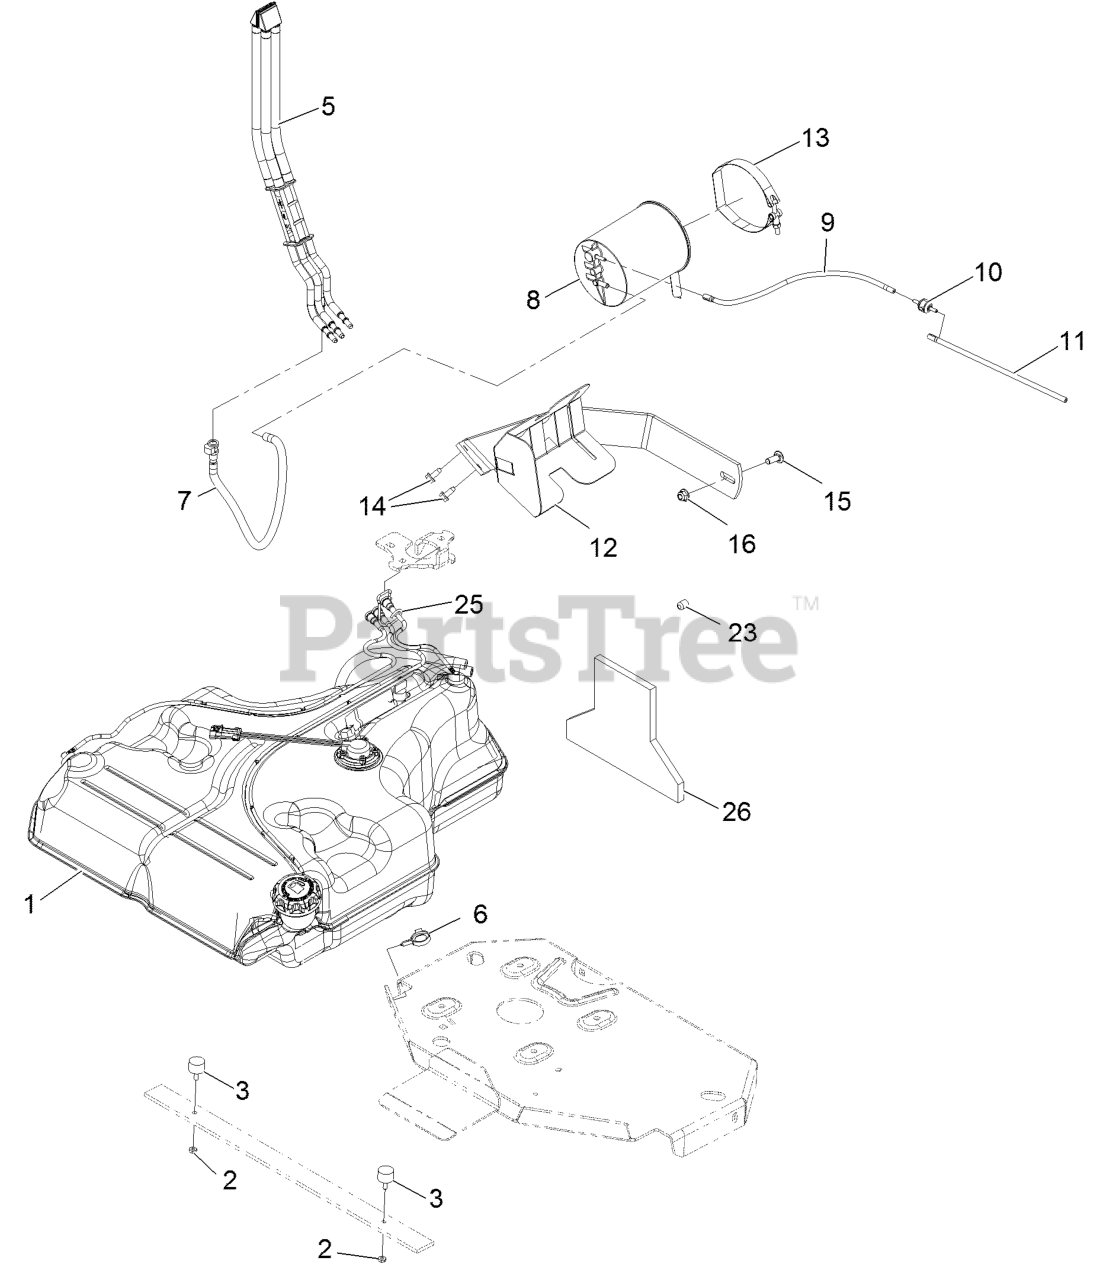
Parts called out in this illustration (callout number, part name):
2	NUT-JAM
5	FUEL MANIFOLD VENT ASM
6	CLAMP-HOSE
7	VENT HOSE ASM
8	CANISTER-CARBON, 1200CC
9	HOSE-VENT, FORMED
11	HOSE-VENT, FORMED
12	MOUNT-CANISTER
13	CLAMP, T-BOLT
14	Screw-HWH 5/16-18 X 3/4 Tf
15	SCREW-CARR
16	NUT-HF, NI
23	PLUG-PORT
25	RETAINER-LINE, VAPOR
26	INSULATION-FOAM, FUEL TAN
